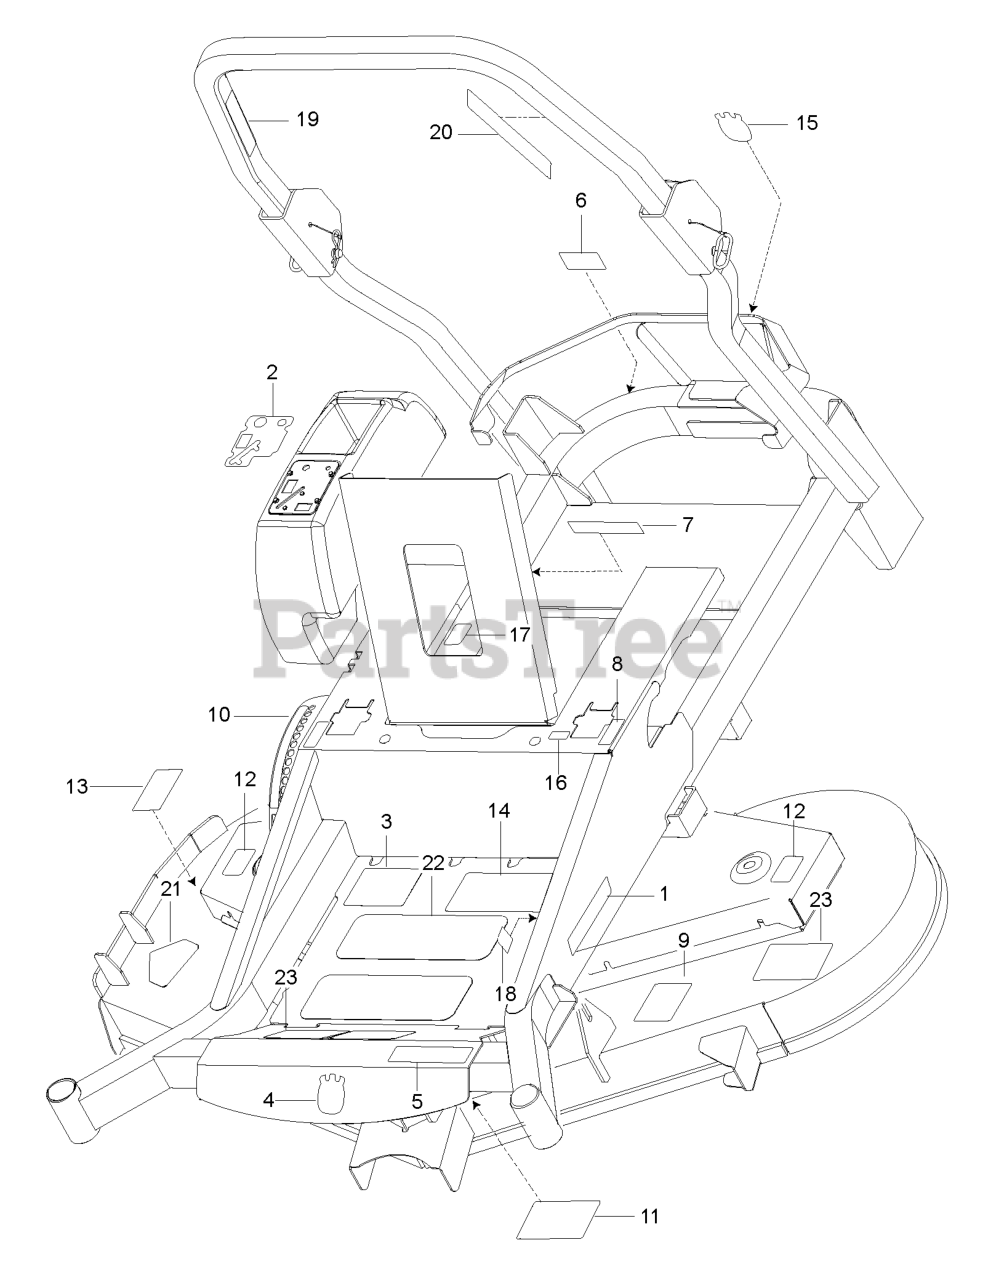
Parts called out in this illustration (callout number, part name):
1	RP.DECAL.BADGE.170MM.TEXTLOGO
2	DECAL, CONSOLE HUS
3	DECAL.ZTR.STRTNGINST.REMOTECHK
4	DECAL.AUGER.HUSQ.CROWN.SNOW
5	DECAL.MZ52
6	DECAL, BELT DRIVE
7	EURO DECAL-BATTERY WARNIN6
8	DECAL.ZTR.MOTCONTRL.SYMBOL.HUS
9	DECAL, BELT ROUTING
10	DECAL, HEIGHT ADJUST
11	DECAL, SERVICE
12	DECAL.DECK.6MIL.EURO.NOSTEP
13	DECAL.DECK.6MIL./DEF.SHLD.WARN
14	DECAL.ZTR.WARNING.SMARTIGNITIN
15	DECAL, CROWN H, 110MM
16	DECAL.STR.S.T.SYSMBOLONLY.2014
17	DECAL CERTIFICATION DECAL EMCC
18	DECAL.80.DBA.AUSTRALIA
19	DECAL, ROPS, WARNING
20	DECAL ROPS
21	DECAL, DECK DEFLECTOR, WARNING
22	ANTI-SKID PAD
